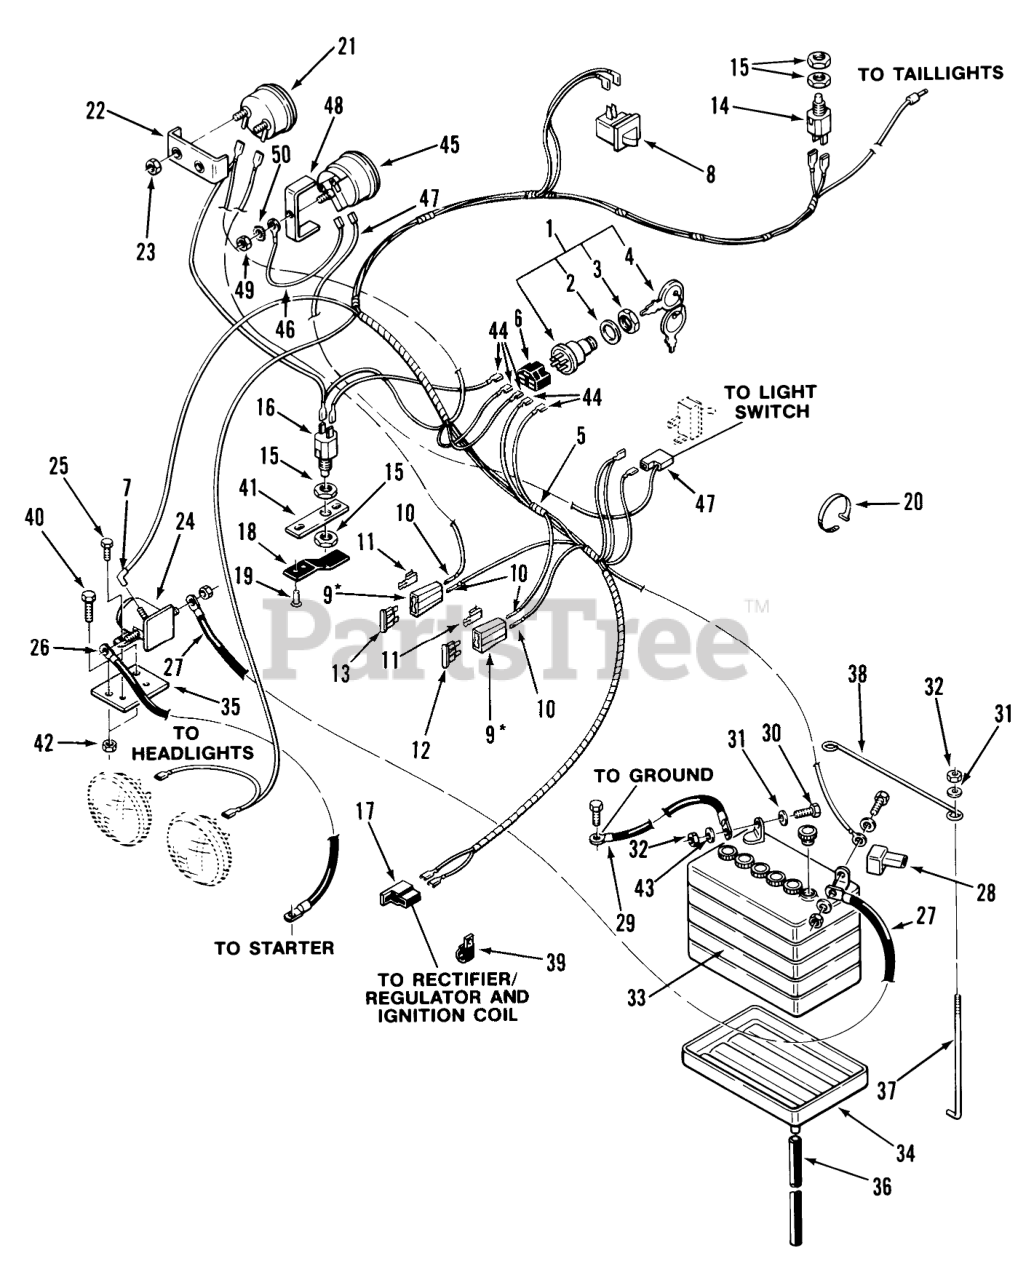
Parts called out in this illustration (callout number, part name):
1	SWITCH-IGNITION
2	LOCKWASHER
4	Key-EL
5	Wiring Harness
6	CONNECTOR-5 WAY-SERV
7	Terminal Part of 5
8	SWITCH INTERLOCK
9	AUTO-FUSEBLOCK TERM
10	TERMINAL-FUSE
12	FUSE-BLADE, 15 AMP
13	FUSE-BLADE, 25 AMP
14	SWITCH
15	NUT-HEX
16	SWITCH
17	CONNECTOR BODY
18	CLIP-SWITCH
19	RIVET
20	PLASTIC TIE
21	Ammeter (Includes 22)
22	CLAMP
23	HEX NUT 10-32 E.S.
24	Solenoid
25	Bolt
26	Battery Cable, Negative
27	Cable-Solenoid To Starter
28	Boot
29	Wire
30	Bolt
32	Nut
33	Battery
34	TRAY-BATTERY
34	TRAY BATTERY
35	Solenoid Bracket
36	TUBE-BATTERY DRAIN
38	ROD-HOLD DOWN
39	CLIP
40	Bolt
41	CLAMP-PTO SWITCH
42	Nut
43	Washer
44	Terminal
45	HOURMETER
46	SY WIRE HR METER G
47	Fused Connector w/6 Amp SFE Fuse
48	HOUR METER CLAMP
49	Hex Nut
50	Lockwasher
